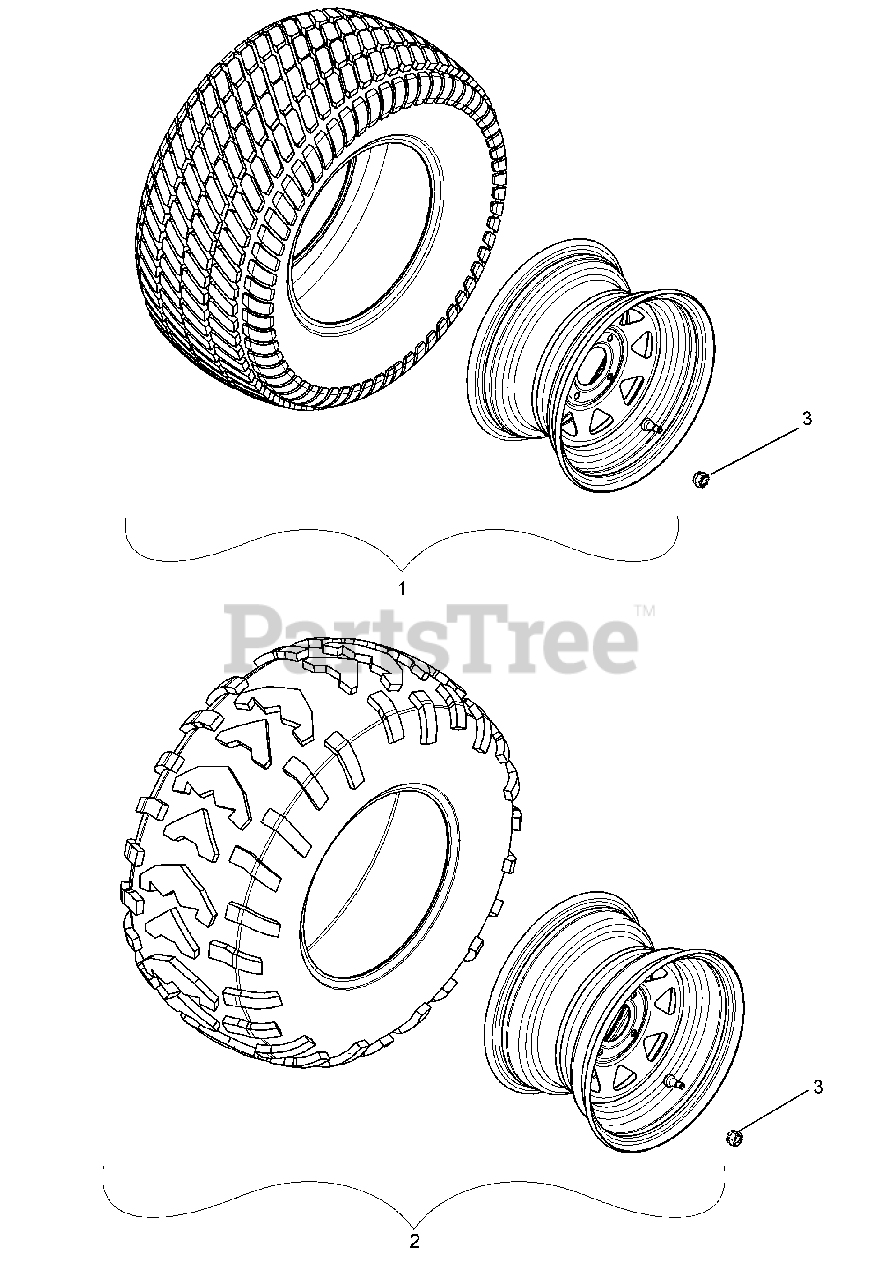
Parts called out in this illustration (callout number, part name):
1	TIRE/WHEEL ASSEMBLY, TREKER TURF REAR (996125)
2	AT TIRE/RIM BLACK RIGHT REAR (996123, 146, 147)
2	AT TIRE/RIM BLACK LEFT REAR (996123, 146, 147)
3	WHEEL NUT .500-20 YZ
